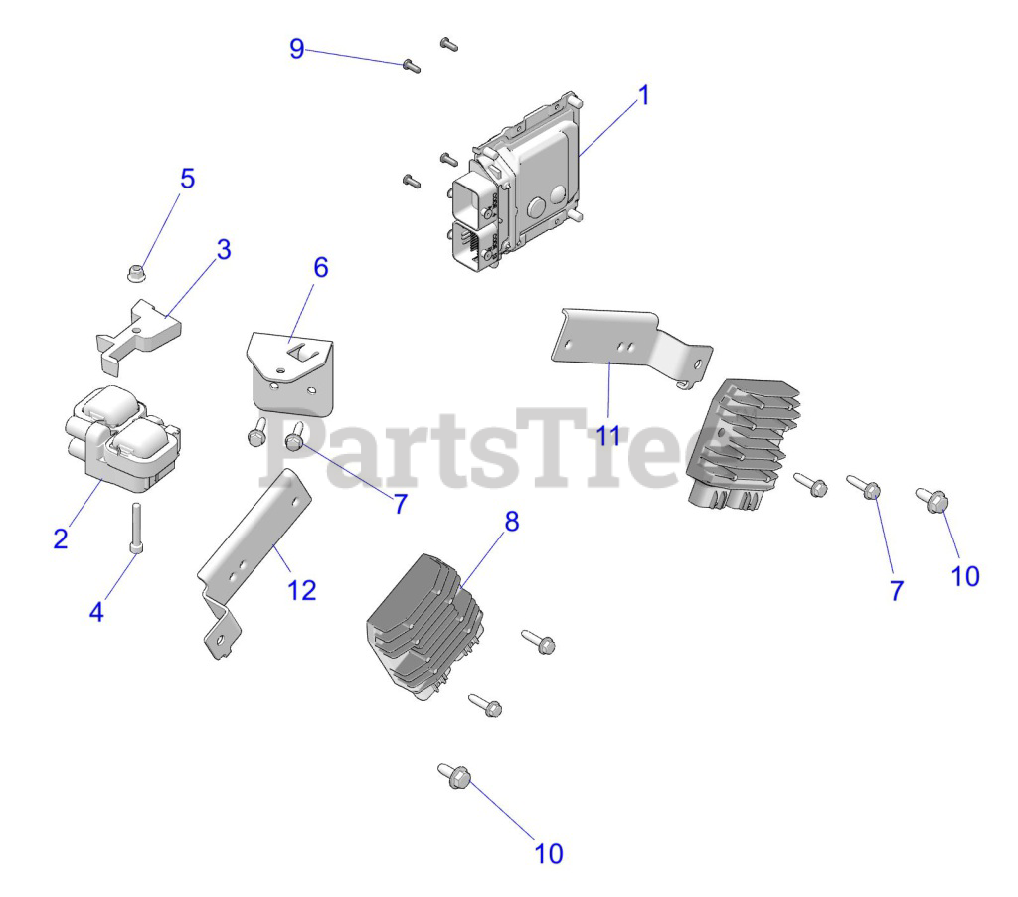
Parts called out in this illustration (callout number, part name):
1	ECM-NO START-ME17
2	COIL, EFI
3	SPACER-COIL MOUNT
4	SCR-M6X1.0X40-HX/SOC/CP-B
5	NUT-M6 FLANGE-NYLOK
6	BRKT-COIL- MOUNT
7	SCR-TFHFL-M6X1.0X25-ZTC
8	REGULATOR-3PH-35A-SERIES-105C
9	SCR-#10X1/2-HI/LO-PN-T25-TRX-M
10	BOLT-M8X1.25X20-HXFLG-TAP/R-OD
11	BRKT-MOUNT-REG
12	BRKT-MOUNT-REG
